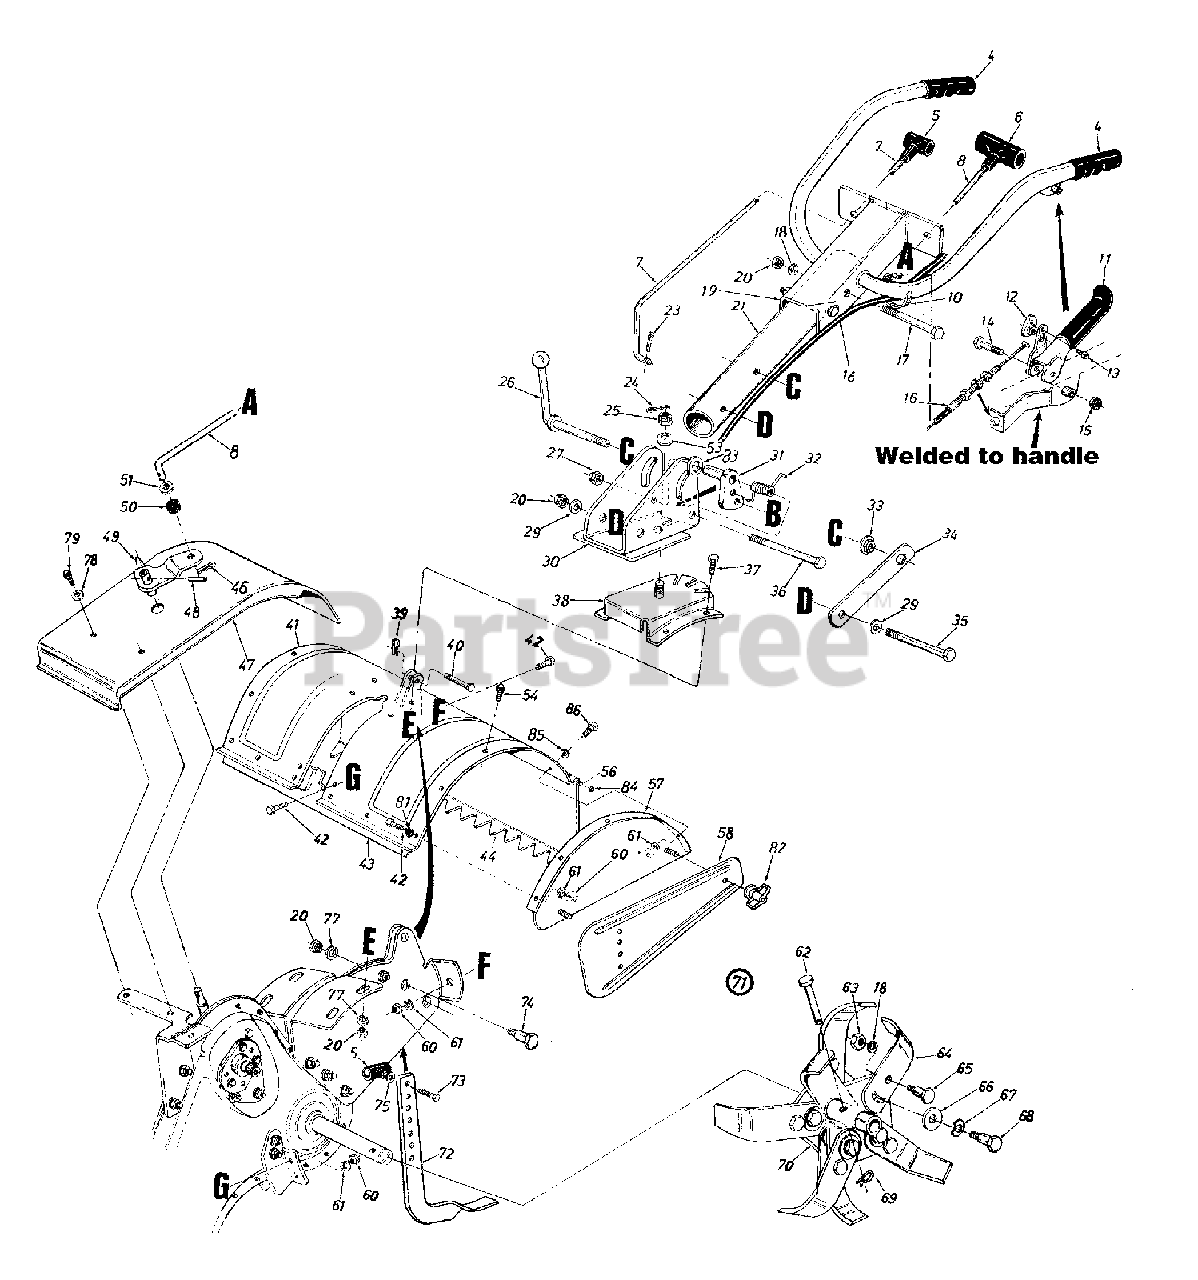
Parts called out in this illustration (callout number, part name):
4	Handle Grip
5	Small "T" Knob
6	Large "T" Knob
7	Clutch Rod
8	Control Rod 37" Lg.
10	Cable Tie-Self Clinching
12	Barrel Cable Hold Down
13	Hex B-Tap Scr. #10 x .44" Lg.
14	Hex Bolt 3/8-24 x 2.25" Lg.
15	Hex Jam L-Nut 3/8-24 Thd.
16	Clutch Control Cable 46" Lg.
17	Hex Bolt 3/8-16 x 3.00" Lg.
18	L-Wash. 3/8" I.D. - H.D.
24	Cotter Pin 3/32" Dia. x 1.25" Lg.
25	Hex Slotted Nut 5/8-18 Thd.
26	Handle Adj. Crank
27	Hex Cent. L-Nut 3/8-16 Thd.
29	Bell-Wash. .4" I.D. x .87" O.D.
32	Spring Handle Adj. (Torsion)
33	Hex Flange Nut 3/8-24 Thd.
34	Bracket Hex Nut Retainer
35	Hex Bolt 3/8-16 x 3.25" Lg.
36	Hex Bolt 3/8-16 x 3.00" Lg. - Gr. 8
37	Hex Bolt 3/8-16 x 1" Lg.
40	Clevis Pin .375" Dia.
43	Bracket Reinforcement - 18"
46	Intern. Cotter Pin 5/16" Dia.
49	Shifting Crank Ass'y.
50	Rubber Washer .33" I.D.
51	Fl-Wash. .4" I.D. x 1.25" O.D.
53	Bell-Wash. .63" I.D. x 1.25"
54	Hex Wash. Tap Scr.
56	Tiller Flap Rod
61	L-Wash. 5/16" I.D.
62	Clevis Pin .375" Dia.
63	Hex Nut 3/8-24 Thd.
65	Shld. Bolt 1/2" Dia. x .175
66	Fl-Wash. .51" I.D. x 1.50"
67	Bell-Wash. .515" I.D. x 1.14"
68	Shld. Bolt 1/2" Dia. x .320
69	Intern. Cotter Pin
73	Hex Bolt 3/8-16 x 1" Lg.
74	Shld. Bolt 1/2" I.D. x .62" Lg.
75	Fl-Wash. 3/8" I.D. x 5/8" O.D.
77	L-Wash. 3/8" I.D.
78	Fl-Wash. .281" I.D. x .62"
79	Hex Wash. Self-Tap Scr. 1/4-20 x .50" Lg.
82	Plastic Knob 5/16-18 Thd.
83	Fl-Wash. .406" I.D. x .875" O.D.
85	Flat Washer .33 x .630 x .06
86	Shoulder Screw
